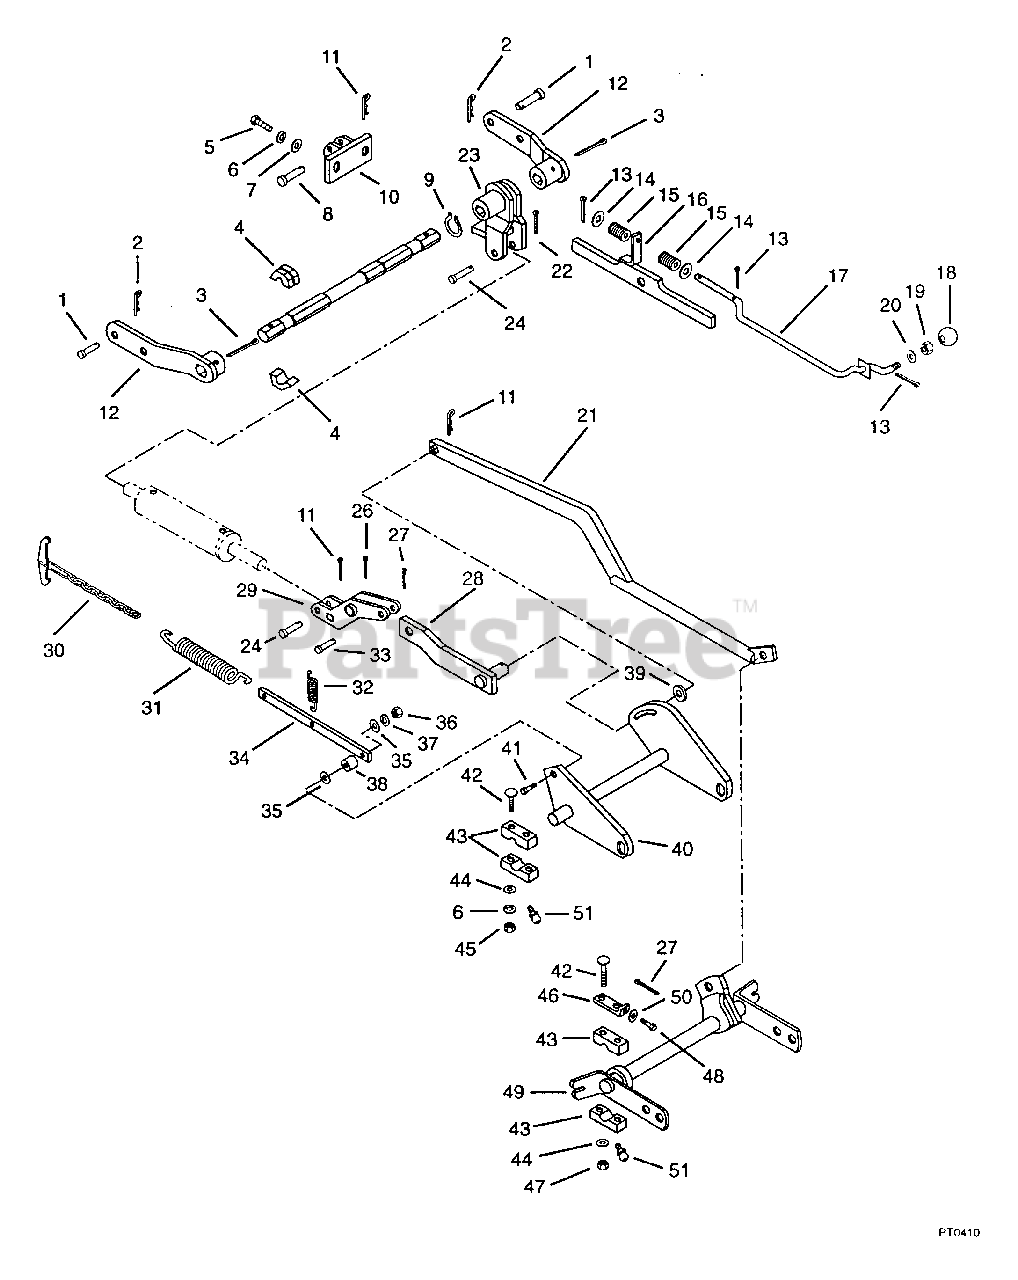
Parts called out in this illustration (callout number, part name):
1	PIN-CLEV .50X1.25 RH ST PL
2	PIN-HAIR INT .14X.4X2.75
3	PIN-COTR .18X2.0 ZCC
4	BSHG-FLG 1.000X1.750X1.000
5	BLT-HEX .38-16X1.00 PL
6	WSHR-LK .375X.094 MED PL
7	WSHR-FL-STL .438X1.0X.083 PL
8	PIN-CLEV .619X2.0 YWZC
9	RG-RTNG-EXT 1.125X.050
11	PIN-HAIR INT .09X.188 PL
13	PIN-COTR .12X.75 PL
14	WSHR-FL-STL.406X.812X.065PL
15	SG-COMP .65X.56X1.50
17	LATCH ROD
18	KNOB-STEERING LOCK
19	NUT-JAM .375-16 PL
20	WSHR-FL-STL .406X1.00X.062 PL
21	LINK - CONNECTOR
22	PIN-COTR .12X1.0 PL
24	PIN-CLEV .494X1.94 YWZC
26	PIN-COTR .18X1.25 PL
27	PIN-COTR .18X1.0 PL
29	BELLCRANK
31	SG-TENS .156X1.062X8.68 WLD ??
32	SG-TENS .035X.45X2.75 WLD 3.5
33	PIN-CLEV .619X1.43 YWZC
35	WSHR-FL-STL.281X.62X.065 PL
36	NUT-HEX .250-20 PL
37	WSHR-LK .250X.077 HVY PL
38	SPACER .269X.375X.343
39	WSHR-FL-STL.812X1.500X.139
40	CENTER ROCKSHAFT
41	BLT-HEX .25-20X1.00 GR2
42	BLT-RDHDSQNK .38-16X2.25 SHTPL
44	WSHR-FL-STL .406X.750X.005
45	NUT-HEX .375-16
47	NUT-LK-CTR .375-16 GR A PL
48	BLT-HEX .31-18X1.25 PL GR5
49	ROCK SHAFT-FRONT
50	WSHR-LK .312X.097 PL HVY
51	FTG-LUBE .25-28X.256 YWZC
